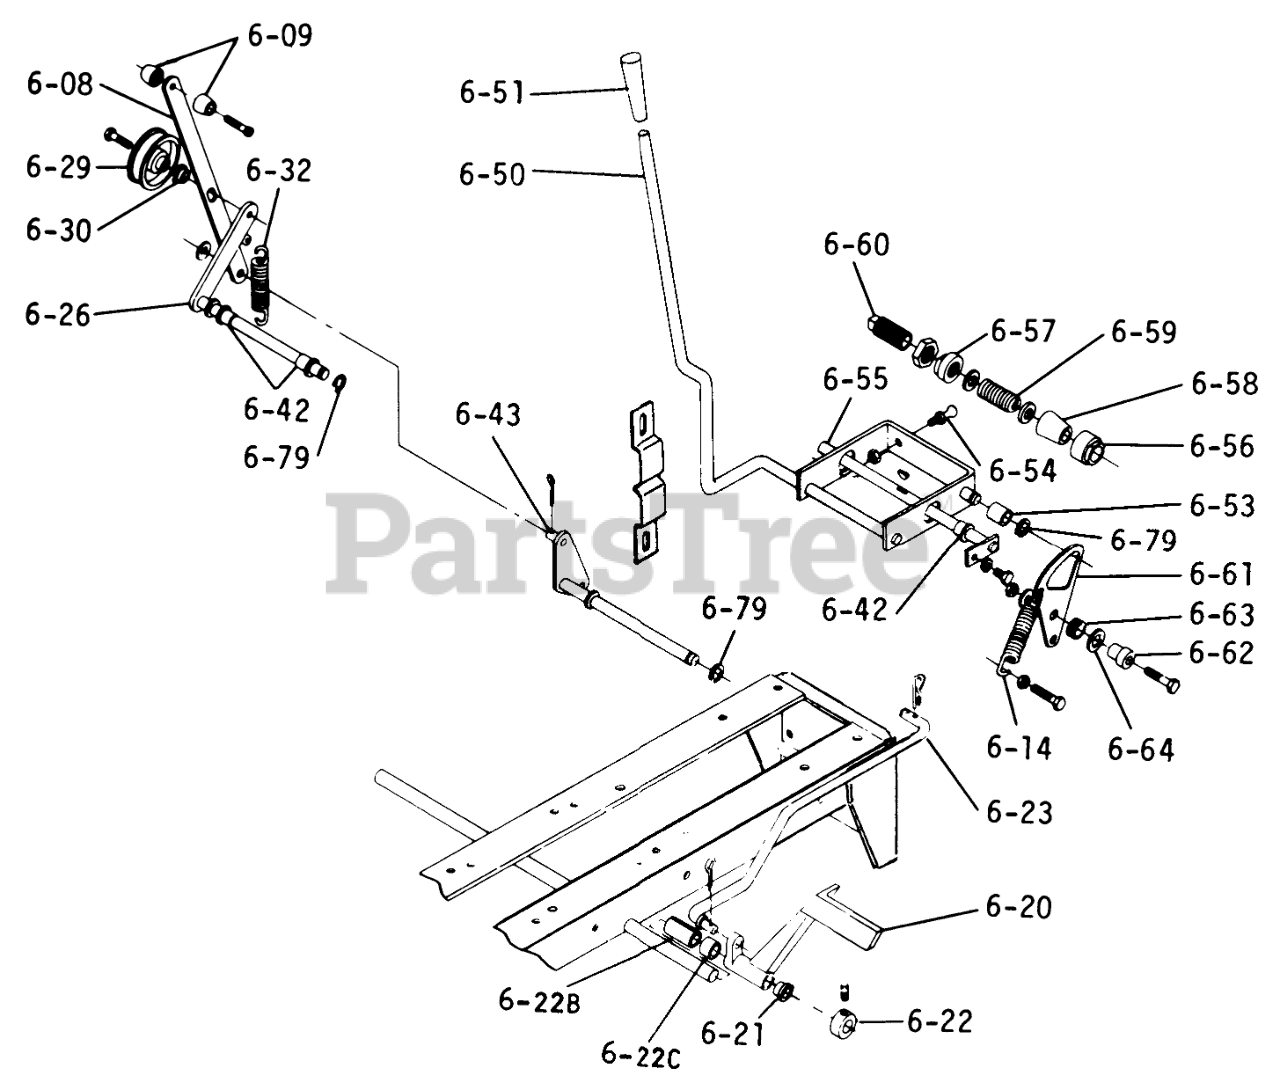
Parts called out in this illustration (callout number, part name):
6-09	KNOB
6-20	PEDAL *R
6-21	BUSHING
6-42	BUSHING-FLANGED
6-51	KNOB
6-53	BEARING-CAM RETURN
6-63	BUSHING-NYLINER
6-64	SHIM-WASHER
